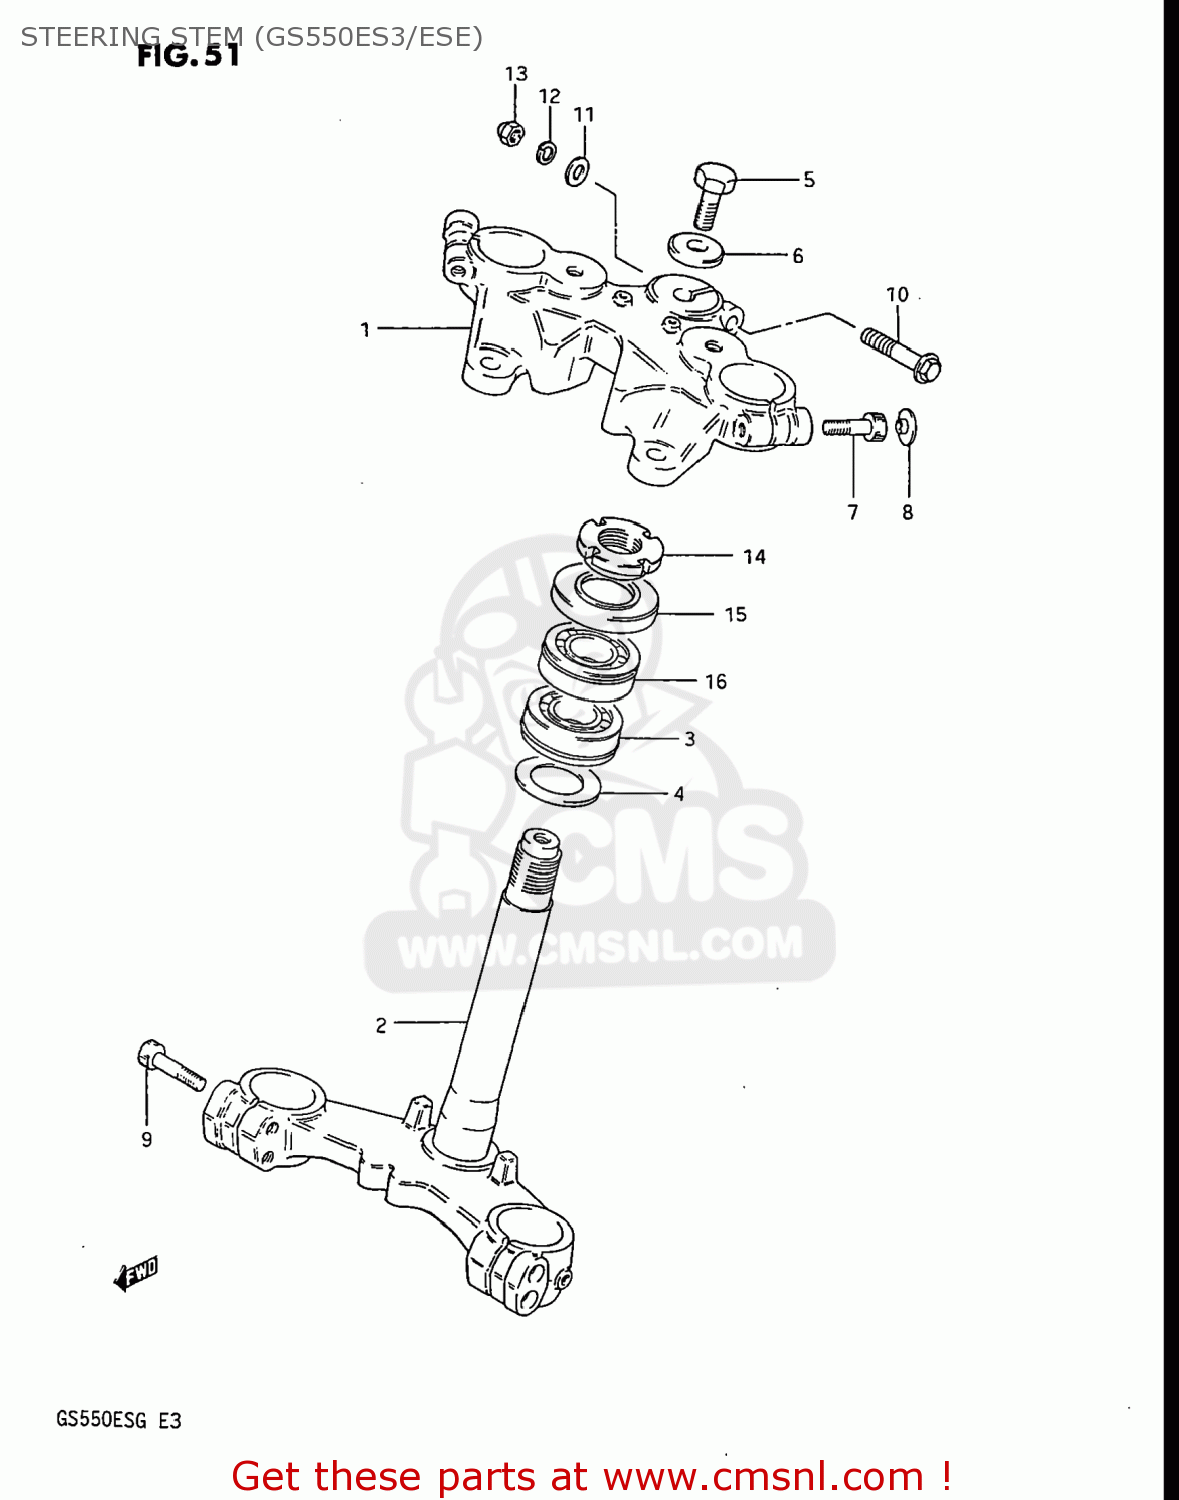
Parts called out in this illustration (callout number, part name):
1	HEAD,STEERING STEM
2	STEM,STEERING
3	BEARING
4	WASHER,THRUST
5	NUT,STEM HEAD
6	SUZUKI
7	BOLT,FORK INNER TUBE FITTING
8	CAP(OD:20)
9	BOLT, REAR (8X30)
10	BOLT, UPPER
11	WASHER
12	WASHER,LOCK,8.
13	NUT,M8X1.25X12
14	NUT,STEERING STEM
15	DUST SEAL,STEERING UPR
16	TAPER,ROLLER BEARING
